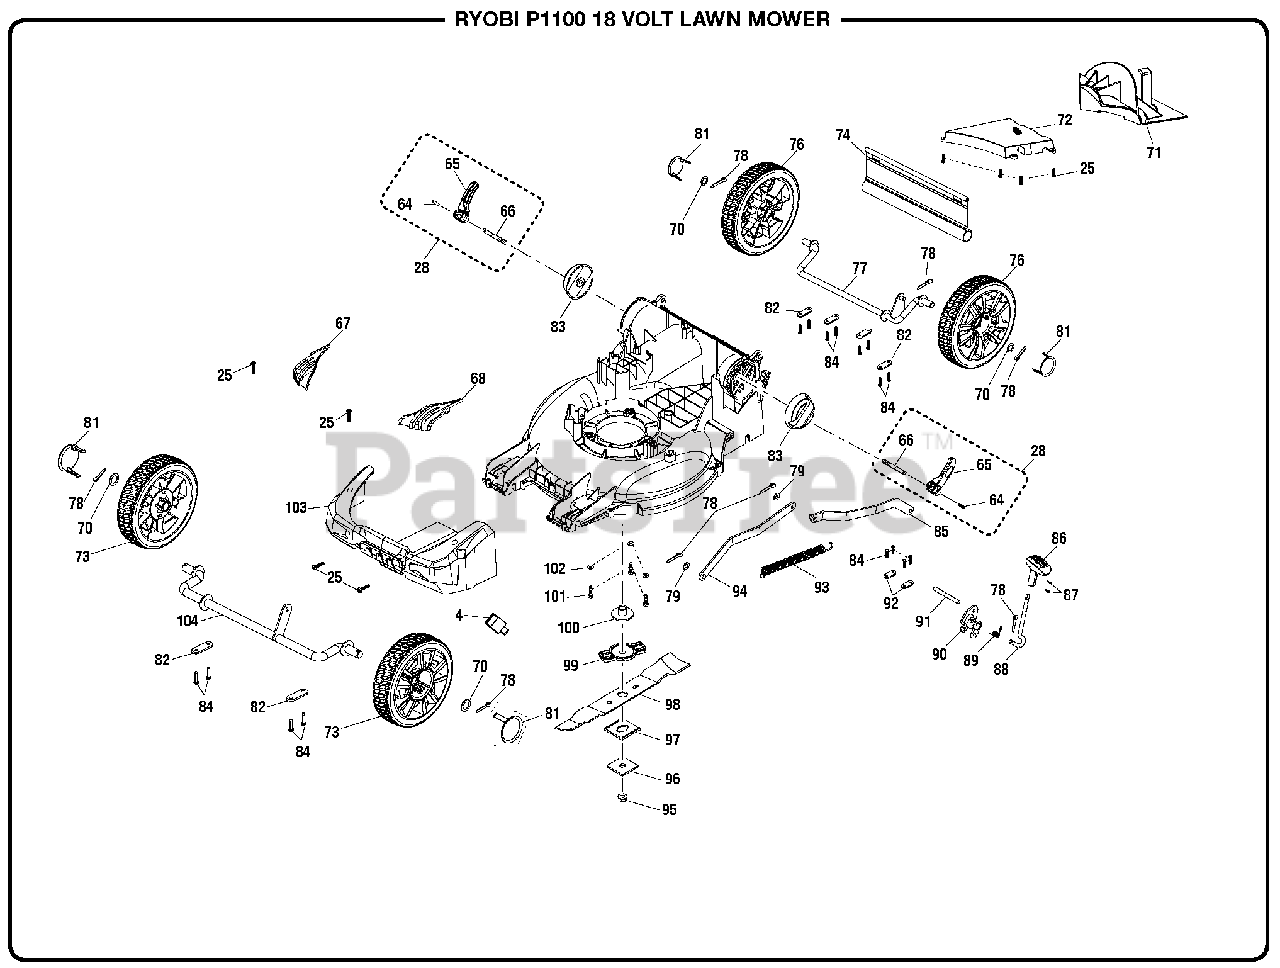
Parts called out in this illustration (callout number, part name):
4	Cord Clamp
25	Screw (M3.5 x 20 mm, T20 Torx Pan Hd.)
28	Handle Lock Assembly
64	Spring Pin
66	Quick Lock Press
67	Grass Protector (Right)
68	Grass Protector (Left)
70	Washer (OD20 x ID13 x 1t)
71	Mulching Plug
72	Rear Cover
73	Front Wheel w/Bearing & Cap
74	Rear Skirt
76	Rear Wheel w/Bearing & Cap
77	Rear Wheel Axle
78	Cotter Pin (2.5)
79	Washer (OD18 x ID8.4 x 1t)
81	Wheel Cover
82	Axle Pressure Plate
83	Base (Lock Handle)
84	Screw (M4 x 18 mm, Torx Pan Hd.)
85	Rear Lift Rod
86	Height Adjustment Handle
87	Screw (M3 x 9 mm, Flat Hd.)
88	Height Adjustment Lever
89	Torsion Spring (Height Adjustment)
90	Height Adjustment Bracket
91	Axle (Height Adjustment)
92	Pressure Plate (Height Adjustment)
93	Retention Spring
94	Front Lift Rod
95	Blade Nut (M10)
96	Blade Retainer
98	Blade
99	Blade Holder
100	Motor Shaft Bushing
101	Bolt (M6 x 16 mm, Hex Hd.)
102	Washer (OD15 x ID6 x 1t)
104	Front Wheel Axle
